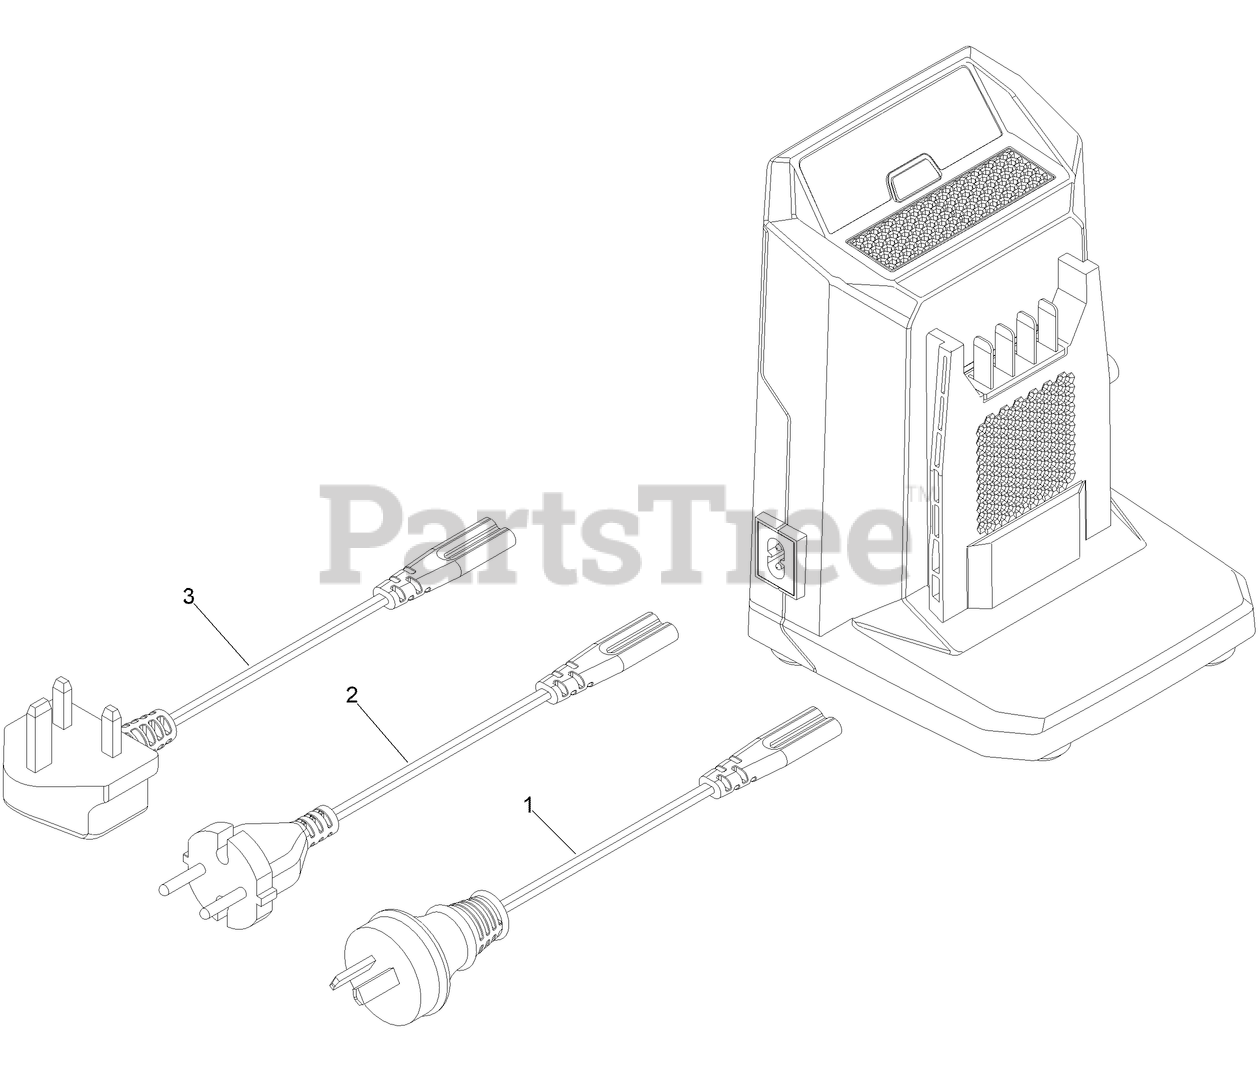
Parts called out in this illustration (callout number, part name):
1	CORD-CHARGER, AU/NZ
2	CORD-CHARGER, CE
3	CORD-CHARGER, UK
